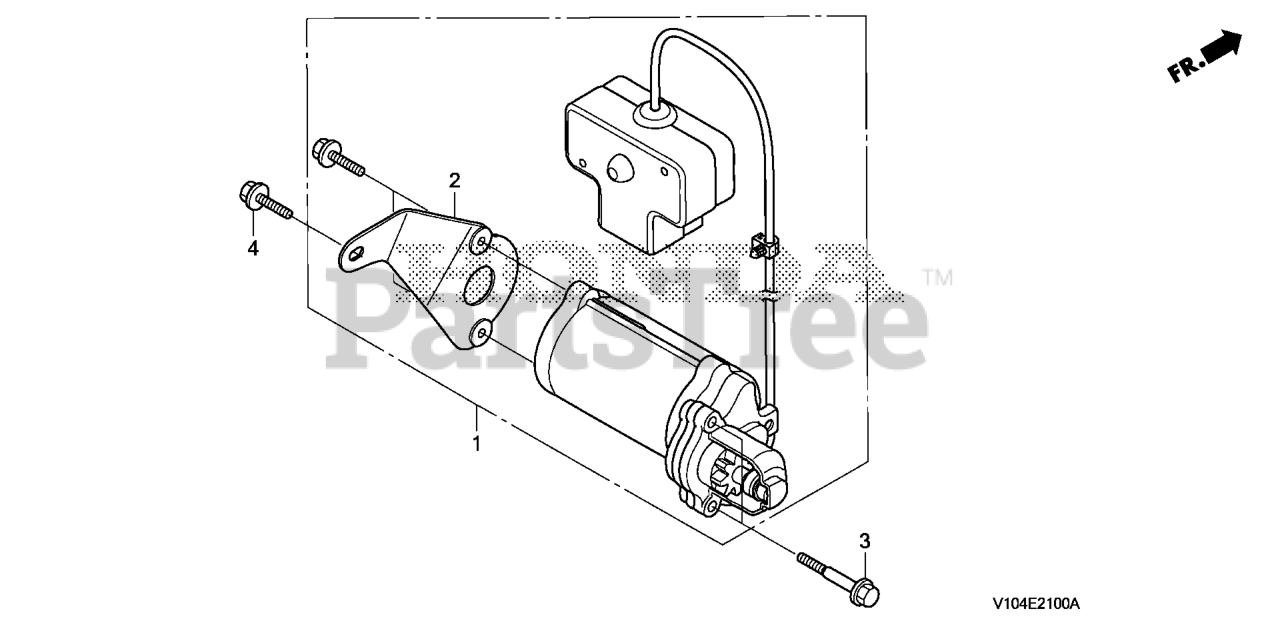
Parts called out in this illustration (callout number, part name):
1	STARTER MOTOR ASSY. (AC)
3	BOLT, SPECIAL (6MM)
4	BOLT, FLANGE (6X14)
